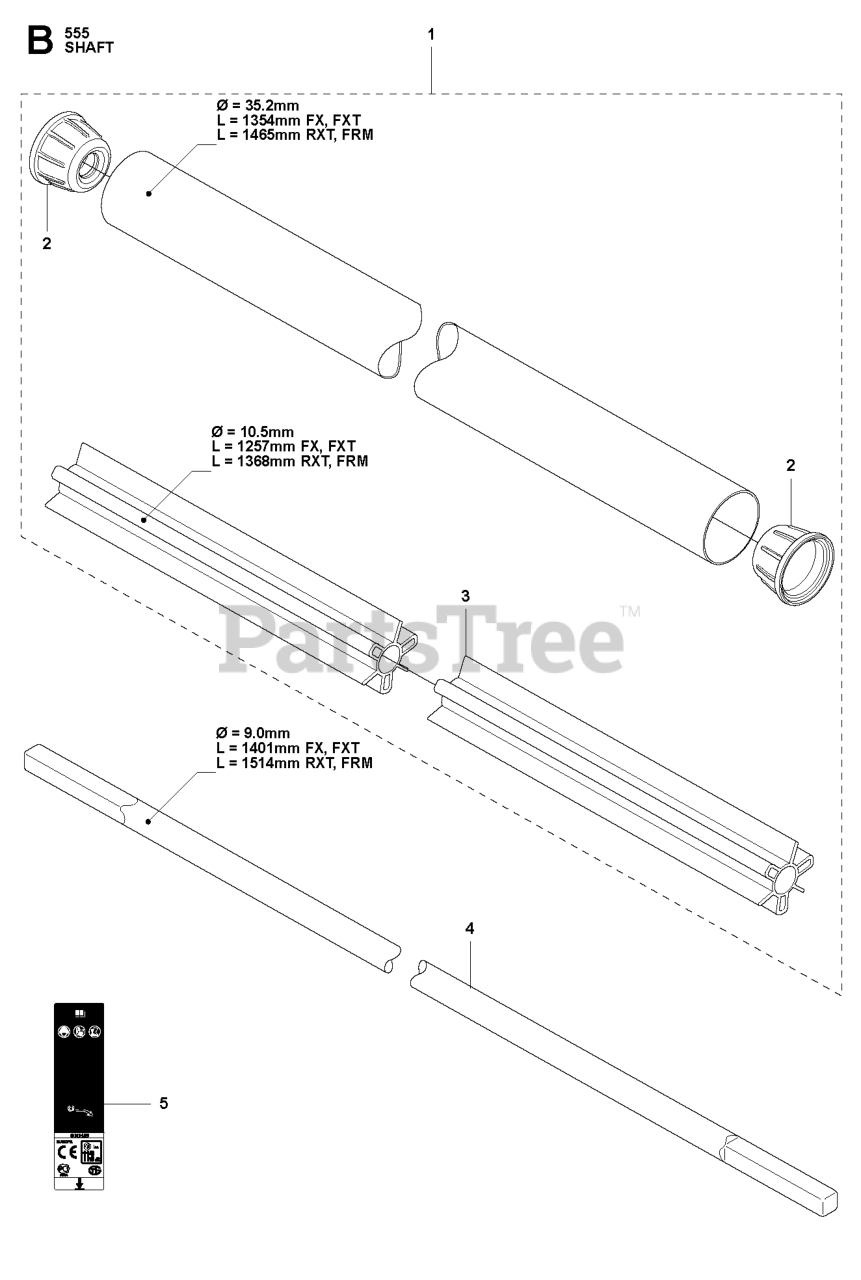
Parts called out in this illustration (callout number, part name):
1	TUBE ASSY
2	RP SPACER
3	BEARING SHAFT
4	DRIVE SHAFT
5	LABEL WARNING TRIMMERS AND BRU
